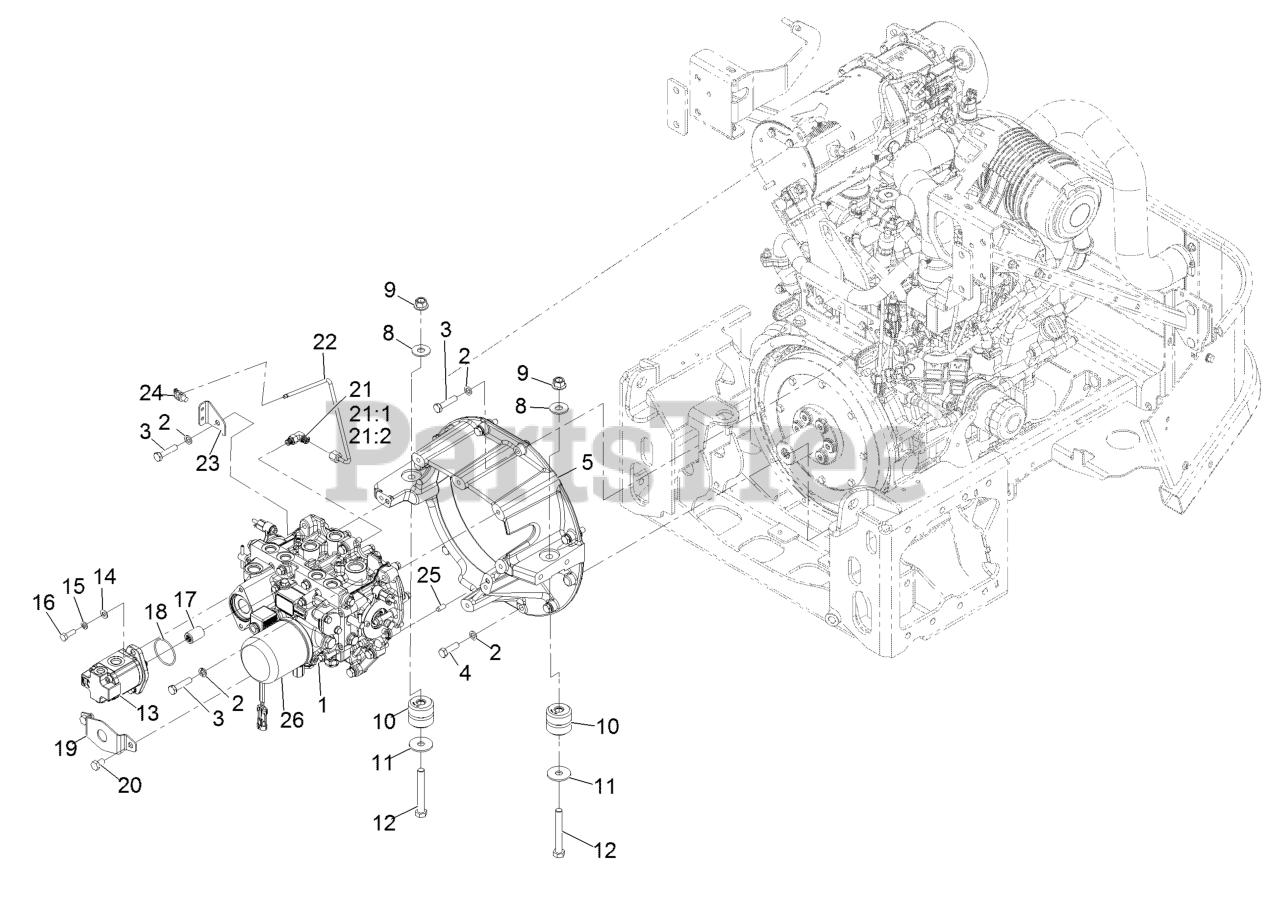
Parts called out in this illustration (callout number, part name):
1	Transmisson ASM
2	Washer-Lock
3	Screw-HH
4	Screw-HH M10-1.5 X 25Mm
5	Housing-Flywheel
8	Washer
9	Nut-Lock 1/2-13
10	Mount-Isolator
12	Screw-HH
13	HYD Gear Pump ASM
14	Washer-5/16 SAE
15	Washer-Lock 5/16
16	Screw-HH M8-1.25 X 25Mm
17	Coupler-Spline
19	Shield-Seal
20	Screw-HH
21	Fitting-Elbow, 90
21:1	O-Ring
21:2	O-Ring
22	Tube ASM
23	Support-Tube
24	Clip-Tie
25	Pin-Dowel
26	Filter-Oil, HYD
